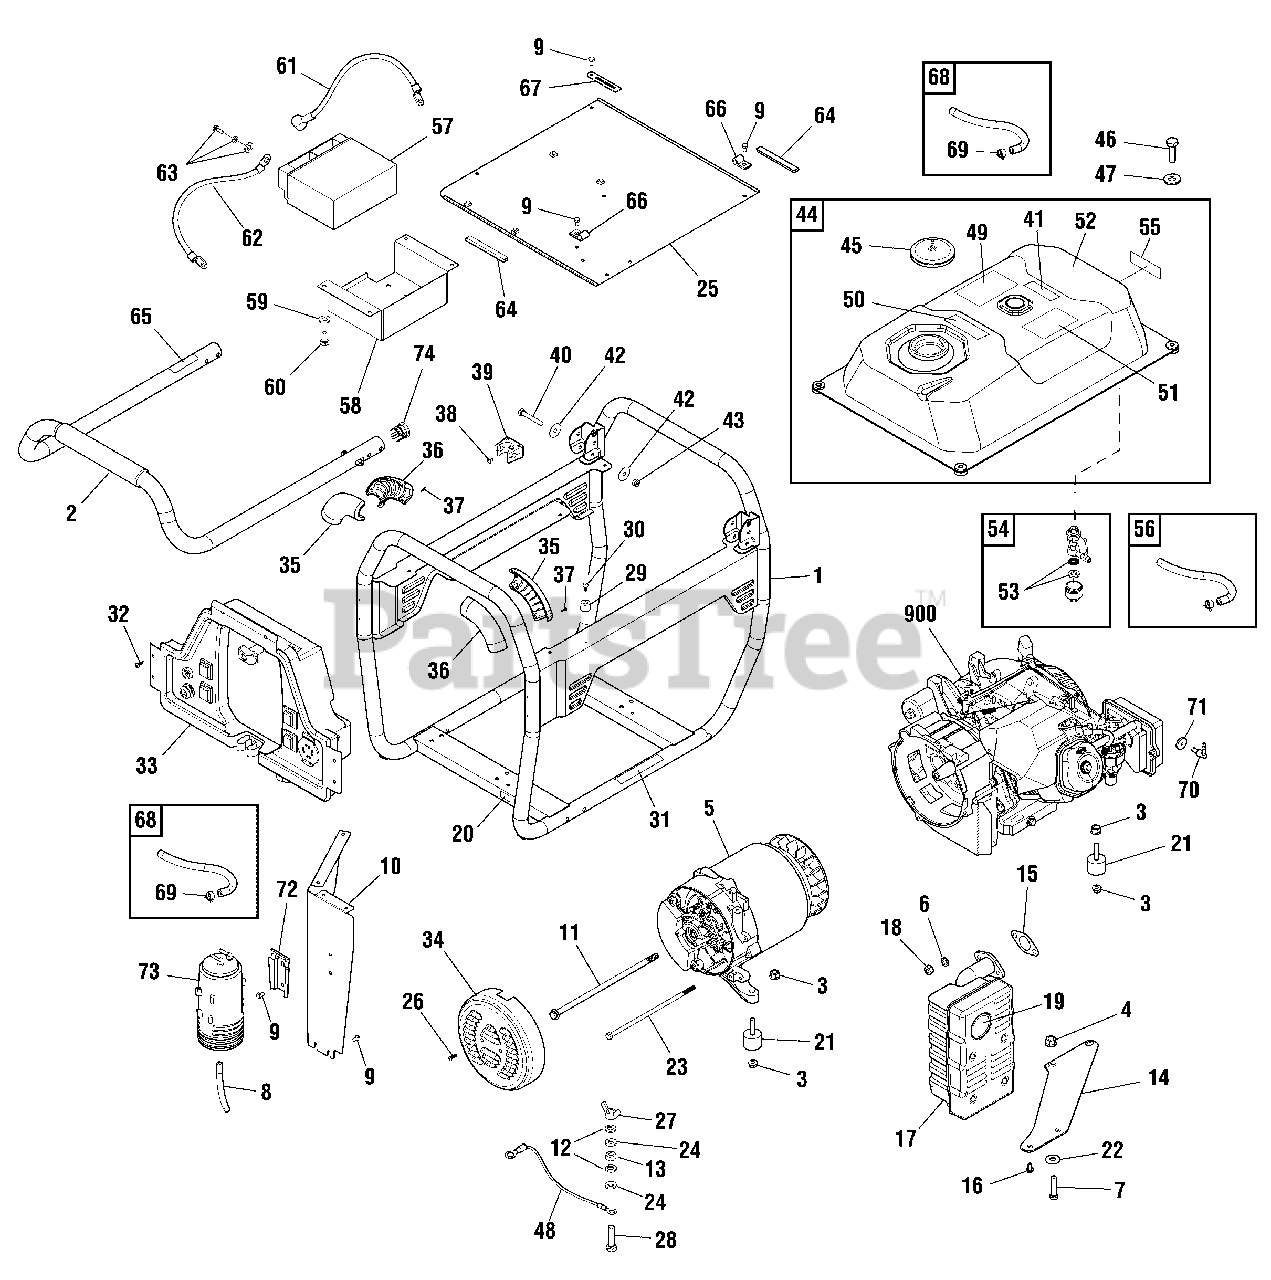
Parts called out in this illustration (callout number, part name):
5	ALTERNATOR
6	* WASHER, Lock, 3/8
7	* CAPSCREW, Hex Head, M10-1.5 x 45
8	HOSE-FUEL
9	* CAPSCREW, Hex Head, M6-1.0 x 10
12	* WASHER, Lock, 1/4
13	* NUT, M6-1.0
15	GASKET-EXHAUST
16	* CAPSCREW, Hex Head, M6-1.0 x 12
18	* NUT, M8 - 1.25
21	MOUNT-VIBRATION
22	WASHER
24	* WASHER, M6
28	* CAPSCREW, Hex Head, M6-1.0 x 25
34	COVER-REAR BEARING
41	DECAL
46	* CAPSCREW, Hex Head, M6-1.0 x 20
47	* WASHER, Flat, 1/4
53	KIT-FUEL VALVE REPAIR
56	KIT-FUEL HOSE
63	KIT-BATTERY HARDWARE
68	HOSE-VAPOR
900	** ENGINE
